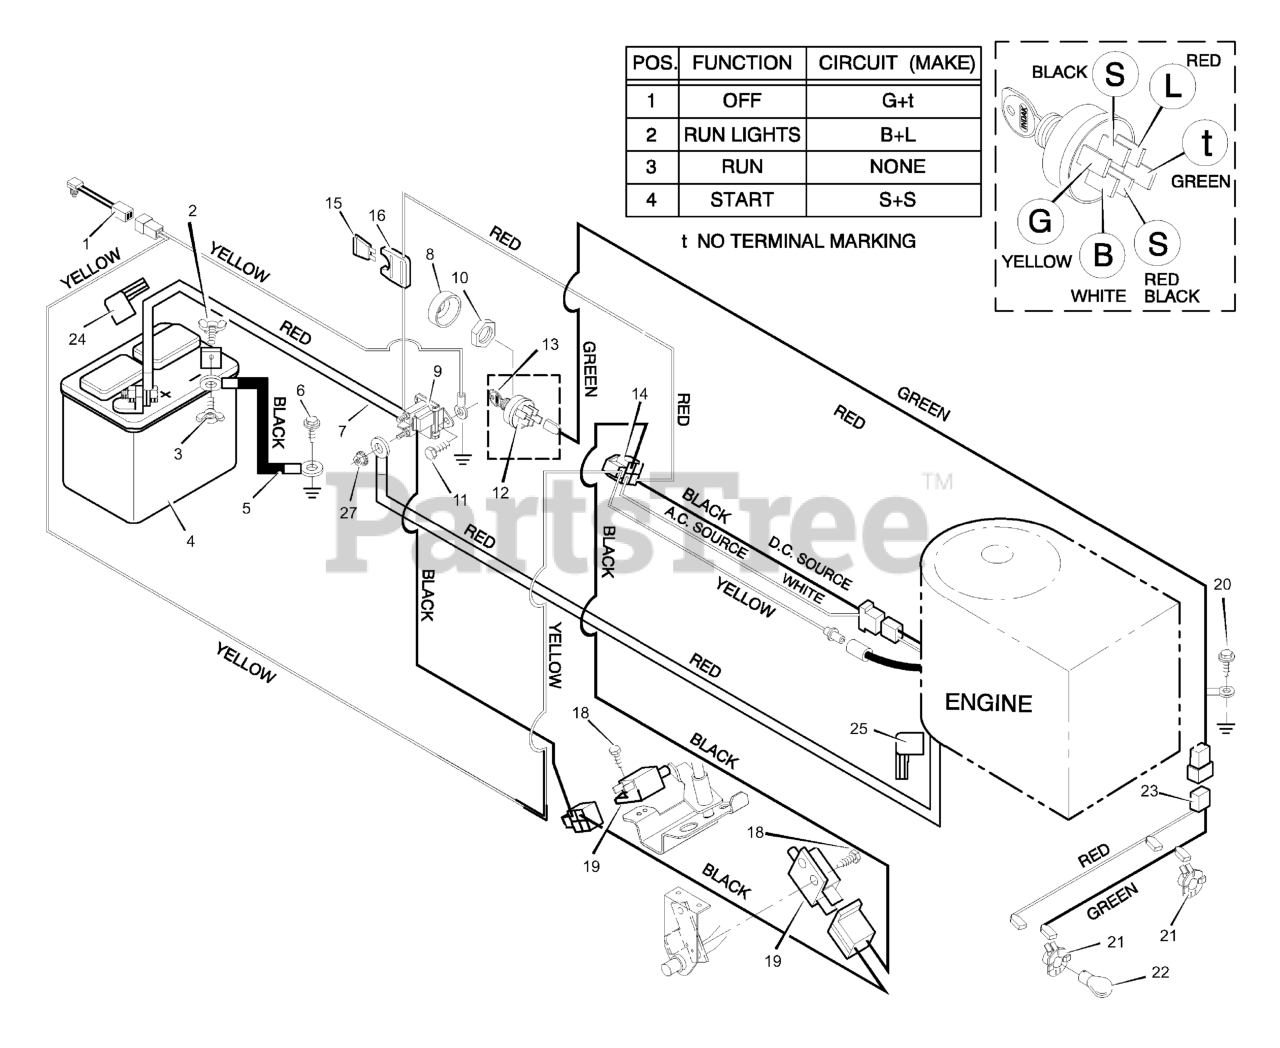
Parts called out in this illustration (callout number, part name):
1	Switch, Seat Sensor
2	Locknut
3	Bolt, Hex
3	Wingnut
4	Battery
5	Cable, Battery Ground
7	Cable, Red Battery
8	Cap, Ignition
9	Solenoid
10	Nut
12	Switch, Ignition
13	Key, Ignition
14	Harness, Chassis Wire
16	Holder, Fuse
19	Switch, Clutch
20	Screw
21	Socket, Light
22	Bulb, Light
23	Harness, Light Wire
24	Cover, Terminal
25	Cover,
27	Locknut
